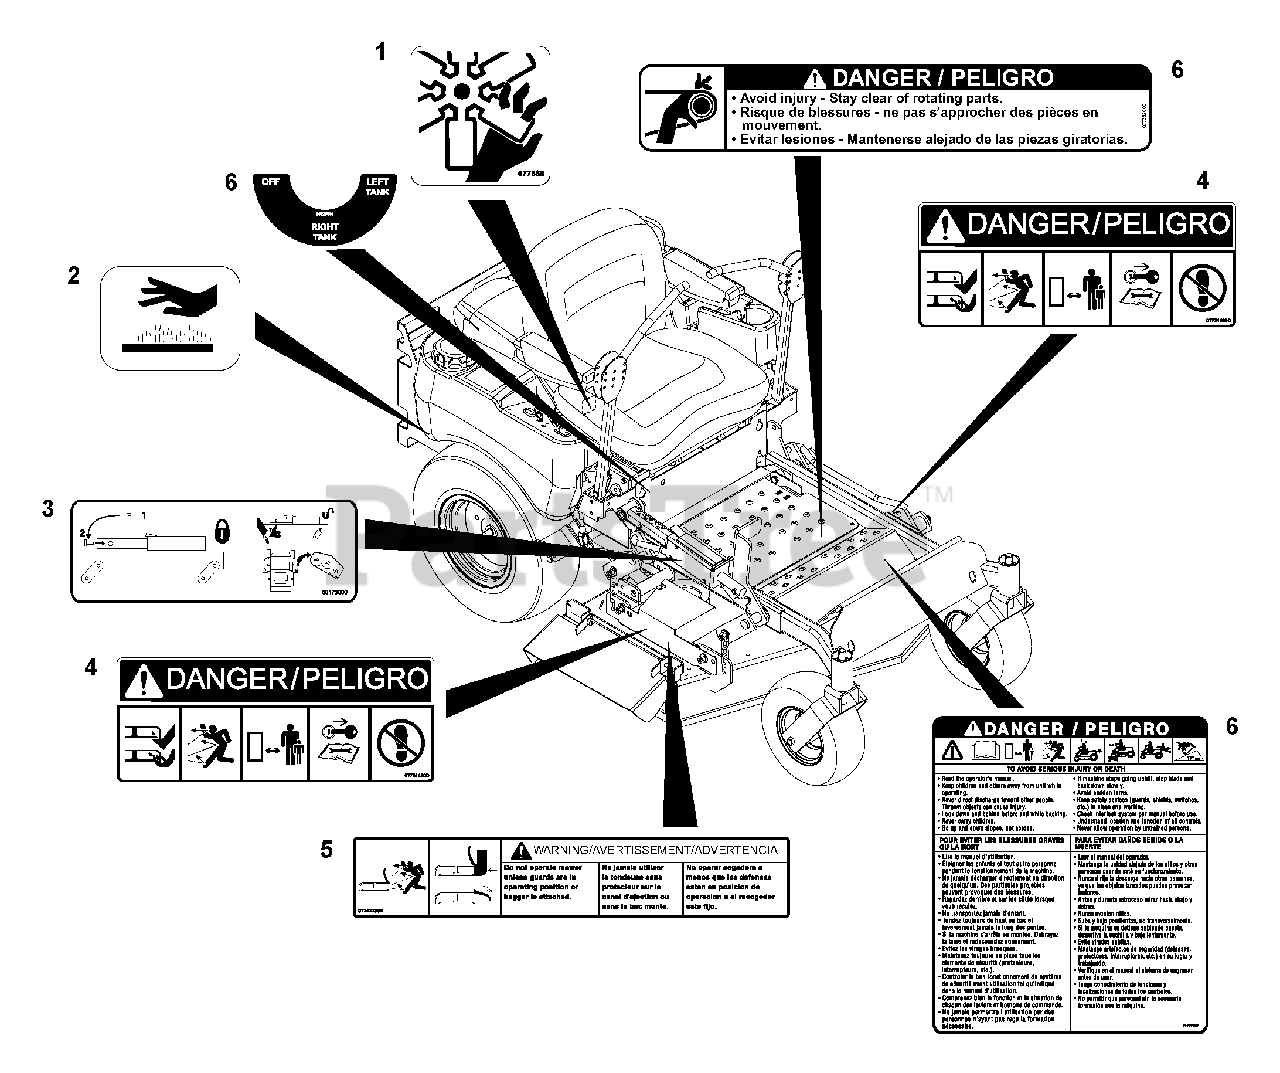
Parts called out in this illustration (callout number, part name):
1	Decal, Danger Fan
2	Decal, Hot Surface
3	Decal, Deck Service
4	Decal, Mower Pan Head Danger
5	Decal, Warning
6	Set, Decal Common Danger/Fuel
